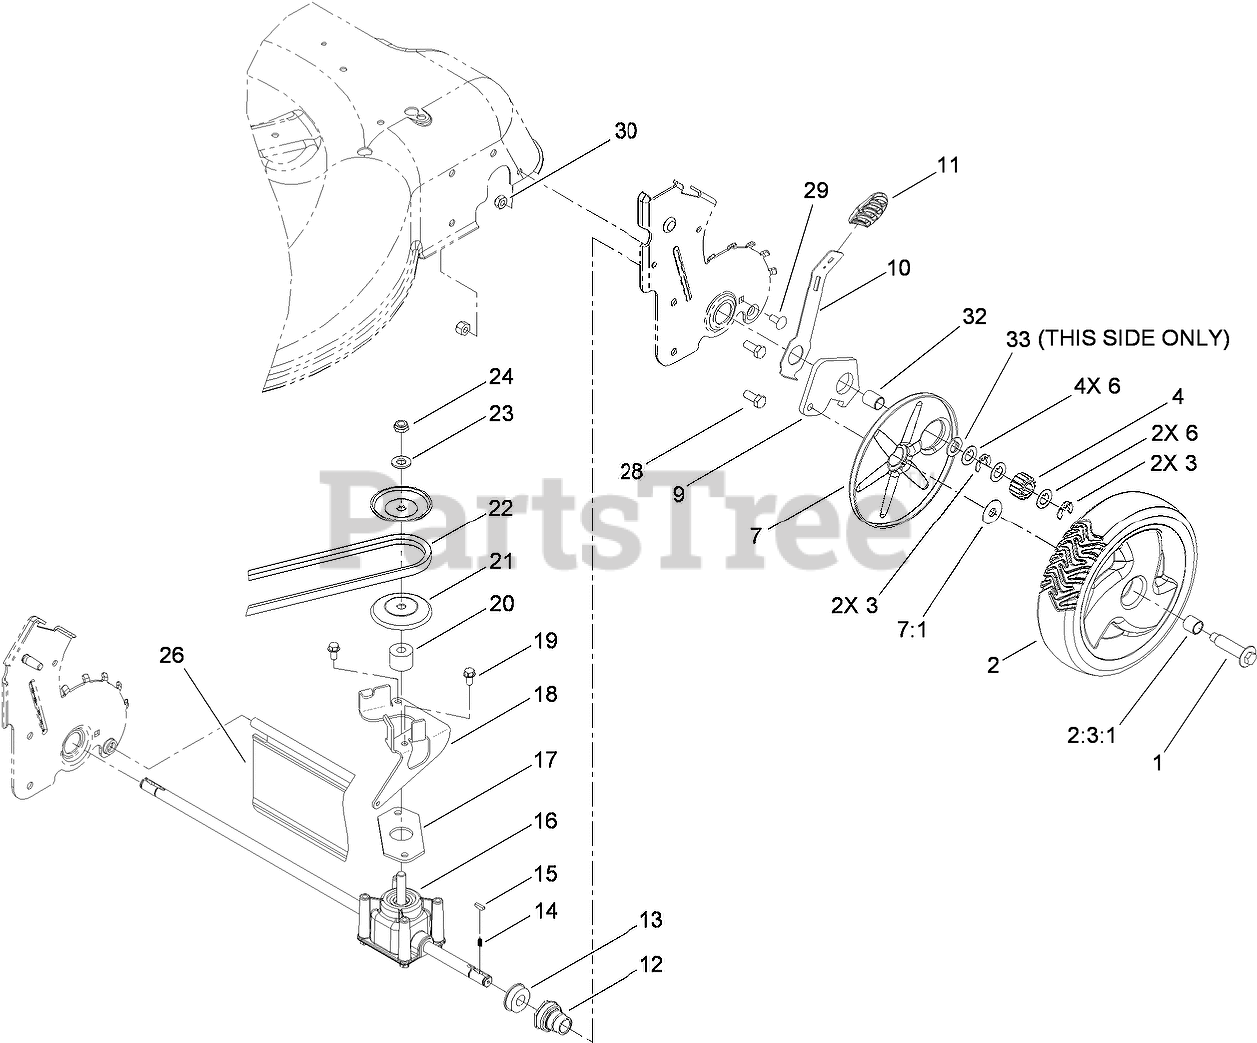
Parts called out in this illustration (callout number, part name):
1	BOLT-SHOULDER
2	Wheel Gear ASM
2:3	WHEEL ASM
2:3:1	BUSHING
3	RING-CLIP, LOCKING
4	Gear-Pinion, 15t
6	Washer-Thrust
7	WHEEL COVER ASM
7:1	WASHER-STEPPED
9	ARM-PIVOT, REAR
10	ARM-SPRING
11	Knob-Lever, HOC
12	RETAINER-BUSHING, HOC
13	BEARING-BALL
14	SPRING-COMPRESSION
16	TRANSMISSION ASM
17	GASKET-GEARBOX
18	BRACKET-PIVOT
19	SCREW-HWH
20	SPACER
21	PULLEY-HALF
22	BELT-V
23	WASHER-FLAT
24	NUT-HEX
26	SHIELD-TRAILING
28	SCREW-HH
29	SCREW-CARR
30	NUT-LOCK, NI
32	BUSHING-SLEEVE
33	WASHER-THRUST
